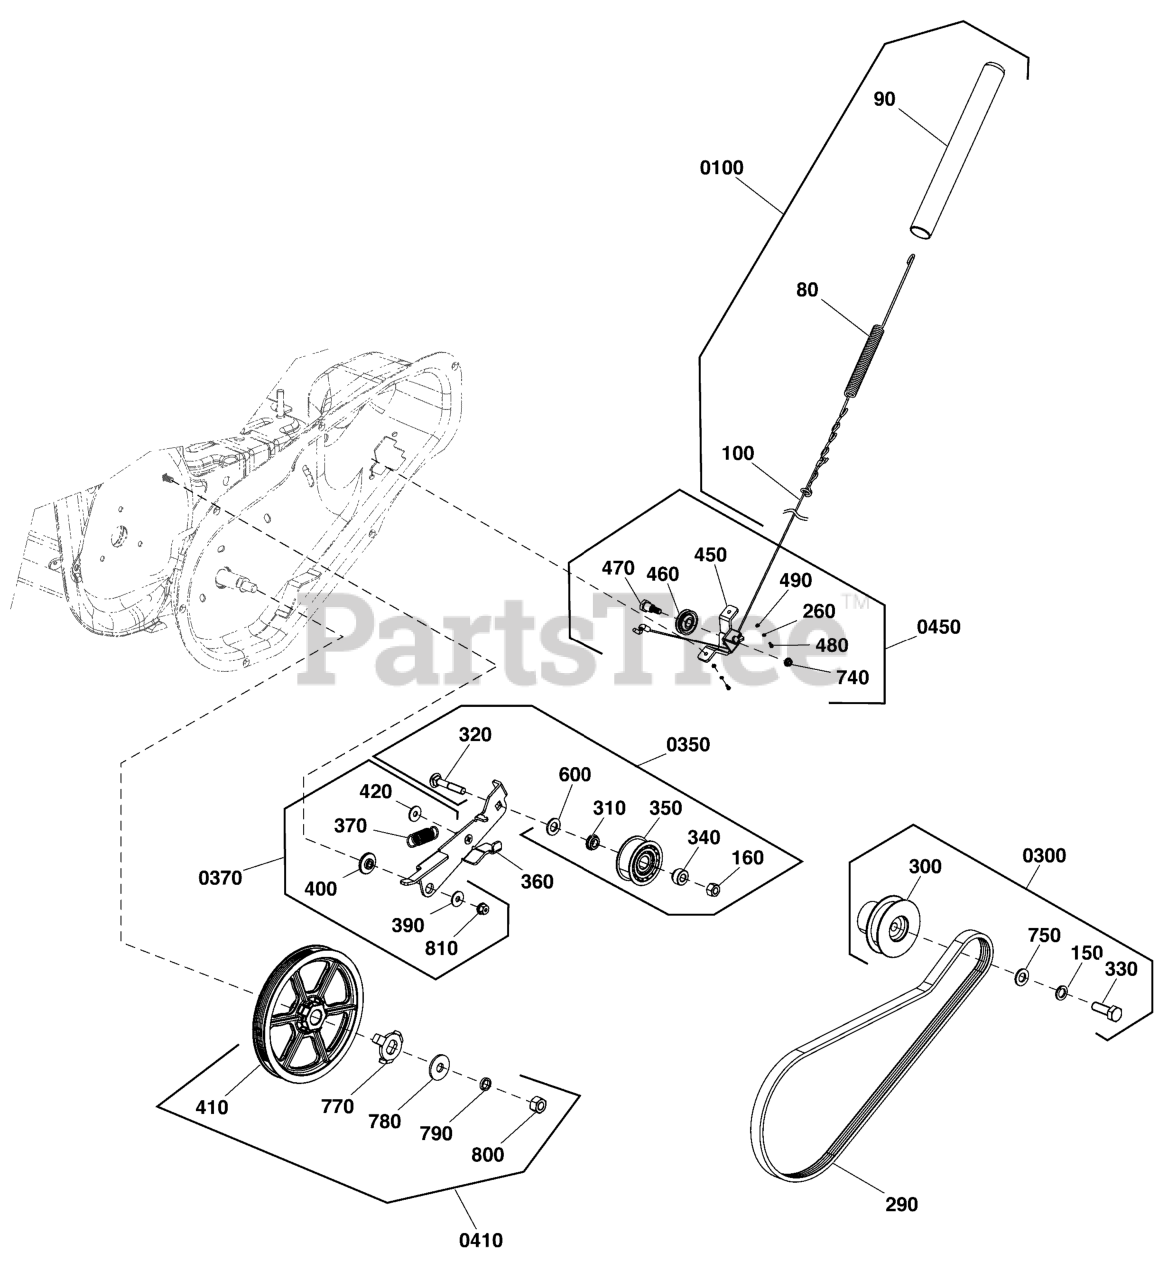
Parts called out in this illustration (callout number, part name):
80	SPRING, Cable
90	SLEEVE, Rubber
0100	KIT, AUGER CABLE
100	CABLE, Auger
150	WASHER, M10, Split Lock
160	NUT, M8, Lock
260	WASHER, M6, Split Lock, MC
290	BELT, Drive
0300	KIT, ENGINE PULLEY
300	PULLEY, Driver
310	Spacer, 8.5 ID, 18 OD, 6 Thick, Shoulder
320	BOLT, M8x40, Carriage
330	SCREW, 3/8-24 x 1, Hex Head
340	SPACER, Idler Pulley
0350	KIT, IDLER PULLEY, TENSION PLATE
350	PULLEY, 8 ID, 53 OD, 22 Wide, Idler
360	PLATE, Tension
0370	KIT, HARDWARE, IDLER BRACKET
370	SPRING, Tension
390	WASHER, 6 X 18 X 1.5, Flat
400	SPACER, Idler Arm
0410	KIT, AUGER PULLEY
410	PULLEY, Driven
420	WASHER, 8x22x2, Flat
0450	KIT, CABLE BASE, AUGER DRIVE
450	BRACKET, Cable Guide
460	PULLEY, Cable
470	SCREW, M6 X 12, Hex Head Shoulder
480	SCREW, M6 1.0X12MM, Hex Head, CZ
490	WASHER, 6x12x.7, Flat
600	WASHER, 10x20x1.8, Flat
740	NUT, M6, Flange Head
750	WASHER, 10x28x3, Flat
770	CLAW, Coupling
780	WASHER, 10x25x2, Flat
790	WASHER, M10, Split Lock
810	* NUT, M6, Flange Head, Lock
